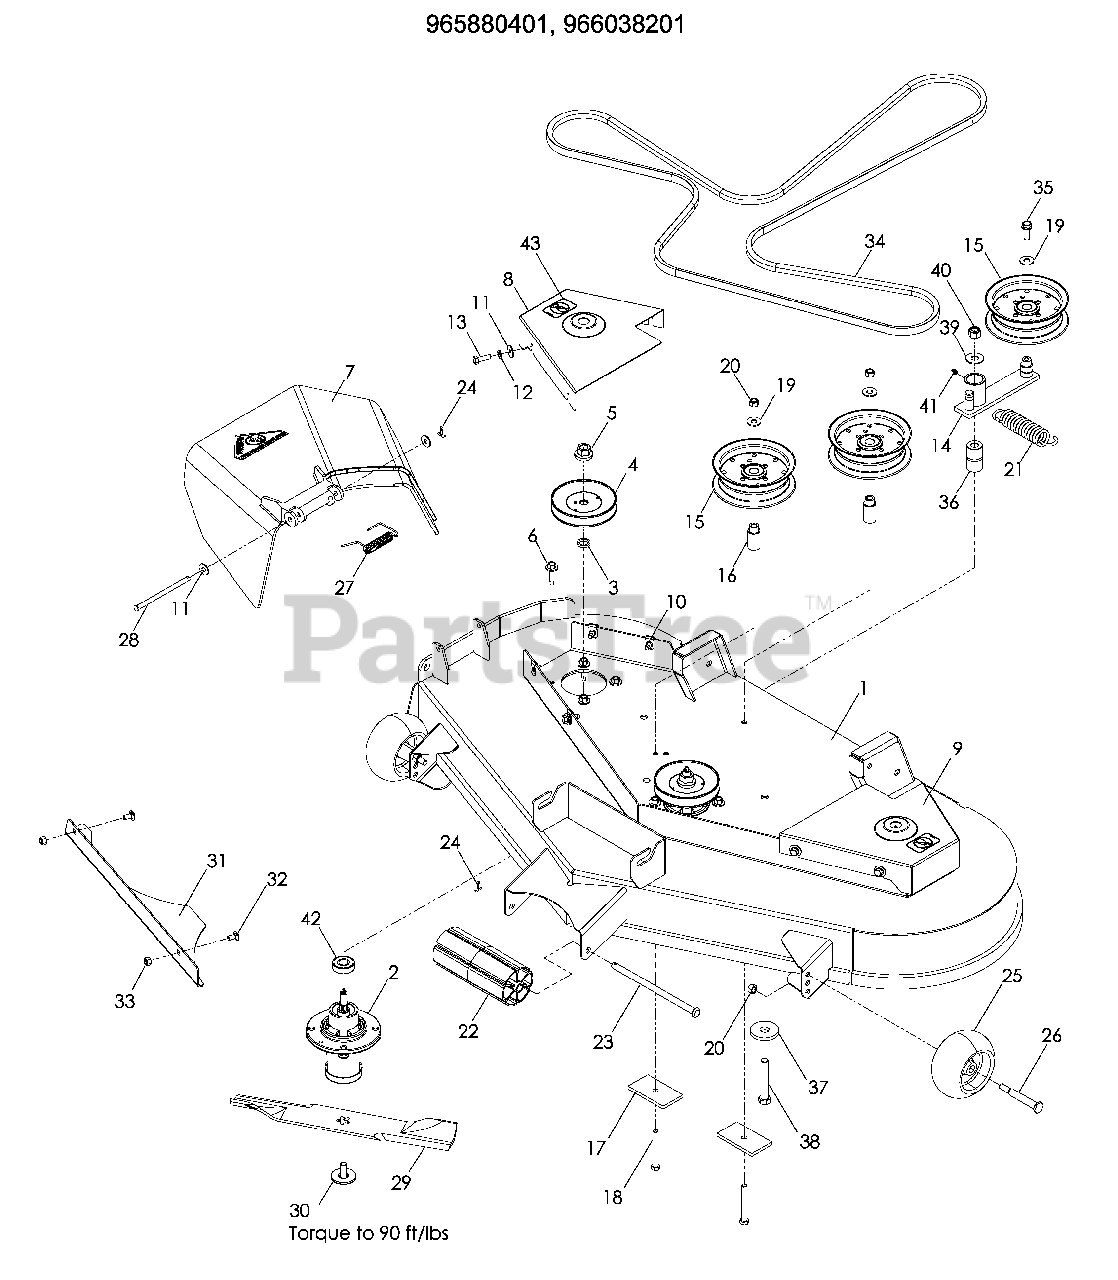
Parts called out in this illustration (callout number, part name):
1	DECK, w/DECALS
2	HOUSING ASSM
3	WASHER, SPACER
4	PULLEY, MANDREL
5	NUT 9/16 TOP CNTRLK
6	SCREW 5/16 -18 x WSH HD
7	CHUTE, DISCHARGE
8	BELT SHIELD, RT
9	BELT SHIELD, LT
10	RETAINER, U TYPE
11	WASHER 5/16 STD FLAT
12	WASHER 5/16 SLW
13	HCS 5/16-18 x ¾
14	ARM, IDLER
15	PULLEY, IDLER
16	BUSHING, IDLER
17	PAD, PAINTED
18	HCS 3/8-16 x 3
19	WASHER 3/8 FLAT STD
20	NUT 3/8-16 HEX NYLOC
22	ROLLER, NOSE
23	ROD, ROLLER, NOSE
24	PIN, COTTER 1/8 x ¾
25	WHEEL, GAUGE
26	BOLT ½-16 x 25/8 SHOULDER
27	SPRING, TORSION
28	PIN, CLEVIS 5/16
30	BOLT 7/16 BLADE
31	PLATE, CONFINEMENT
32	RHSNB 5/16-18 x 5/8
33	NUT 5/16-18 HEX NYLOC
34	BELT, DECK
35	HCS 3/8-16 x 1 WHIZLK
36	BUSHING, PIVOT
37	WASHER, SUPPORT
38	HCS ½-13 x 3¼
39	WASHER ½ STD FLAT
40	NUT ½ HEX NYLOC
41	ZERK
42	BEARING, BALL
43	DECAL, NO STEP
